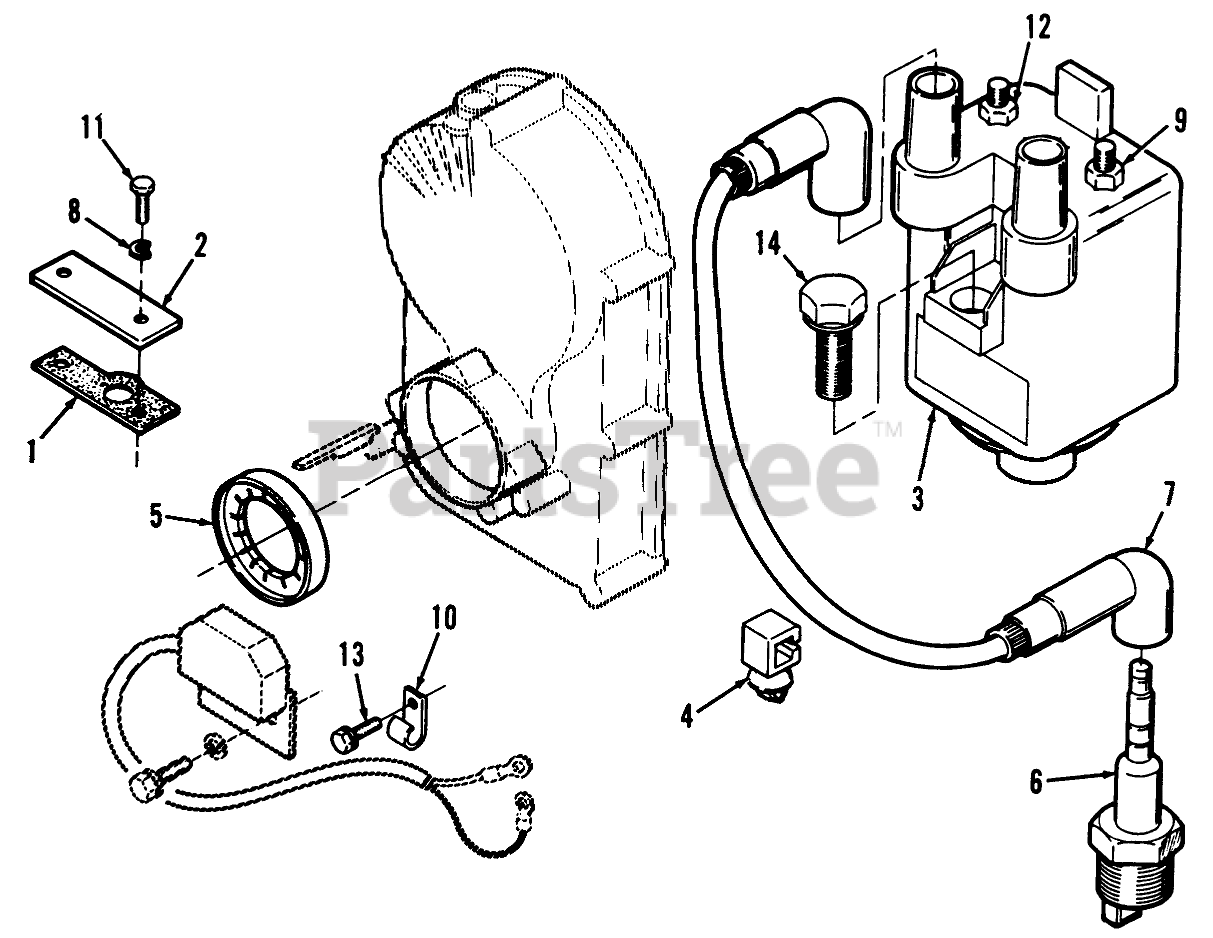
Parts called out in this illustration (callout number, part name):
1	Gasket-Plate
2	PLATE-COVER
3	Coil, Battery Ignition (Includes Nuts)
4	Clip
5	ROTOR-IGNITION
6	Plug-Spark
7	CABLE KIT
8	WASHER-FLAT
9	Nut
10	CLIP-WIRE
11	Bolt
12	Nut
13	Screw-Cap Hex Hd.
14	Bolt
